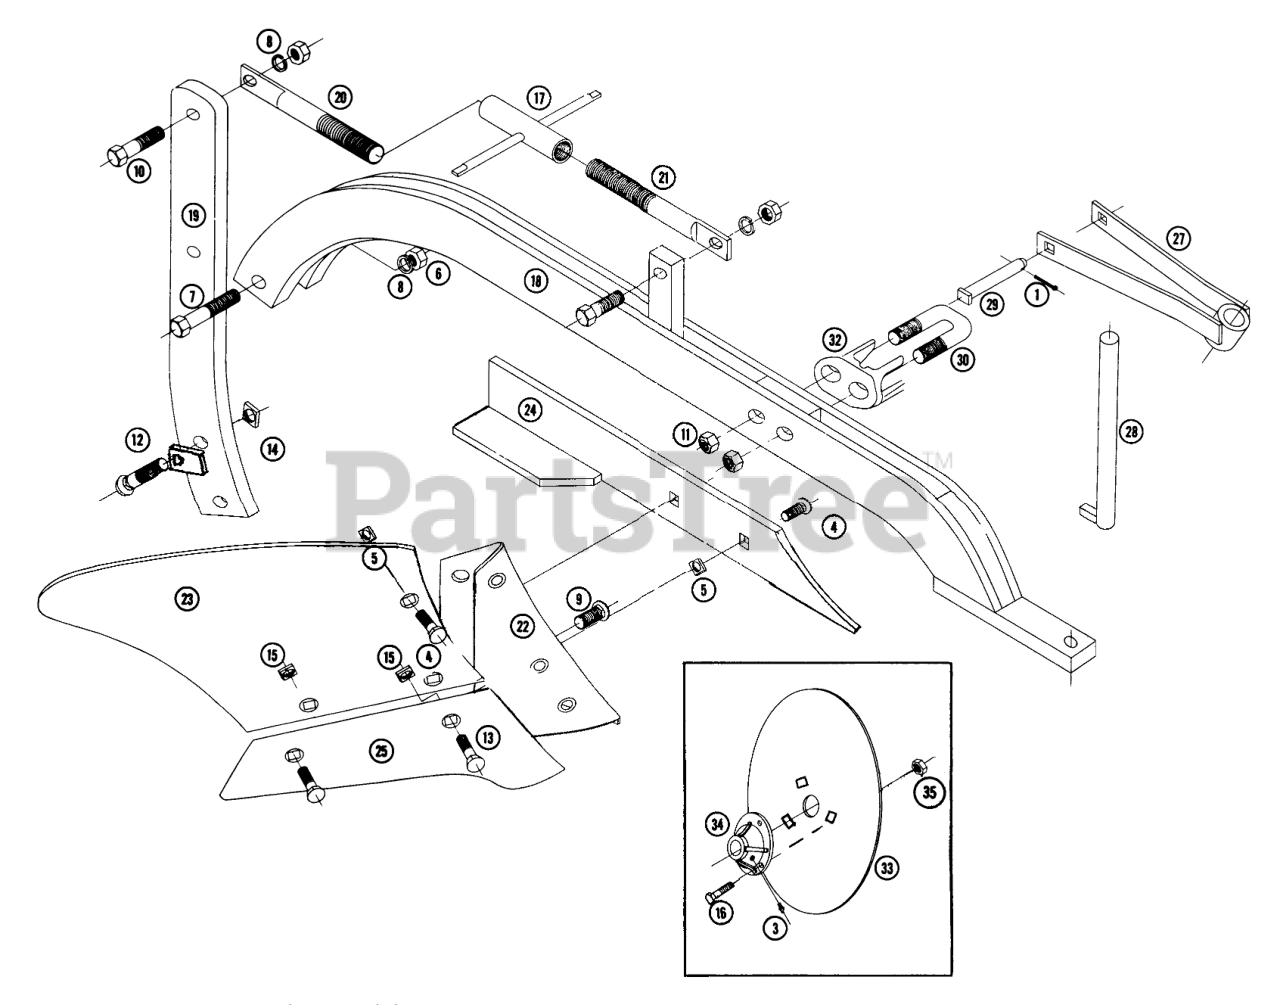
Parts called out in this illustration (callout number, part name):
3	Grease Fitting 5/16 Drive Type
4	Plow Bolt 3/8-16 x 1
5	Nut-Sq. 3/8-16
6	Nut, 1/2-13
7	Bolt-1/2-13-1 3/4
8	Lockwasher
9	Plow Bolt 1/2-13 x 1-3/4
10	Bolt Hex 1/2-13 x 1 1/2
11	5/8 NC Hex Nut
12	Bolt-1/2-13 x 1-1/2 Carr.
14	Nut-Square 1/2-13
15	Nut-Square 7/16-14
16	Bolt Hex 5/16-18 x 3/4
17	Coupling-Adjusting
19	Standard Assembly
22	Frog
23	Mold Board
24	Landslide Assembly
25	Share
27	Standard Assembly
28	Rod-Swivel
29	Pin-Pivot
30	U Bolt
32	Clamp Coulter
33	Blade
34	Hub-Blade
